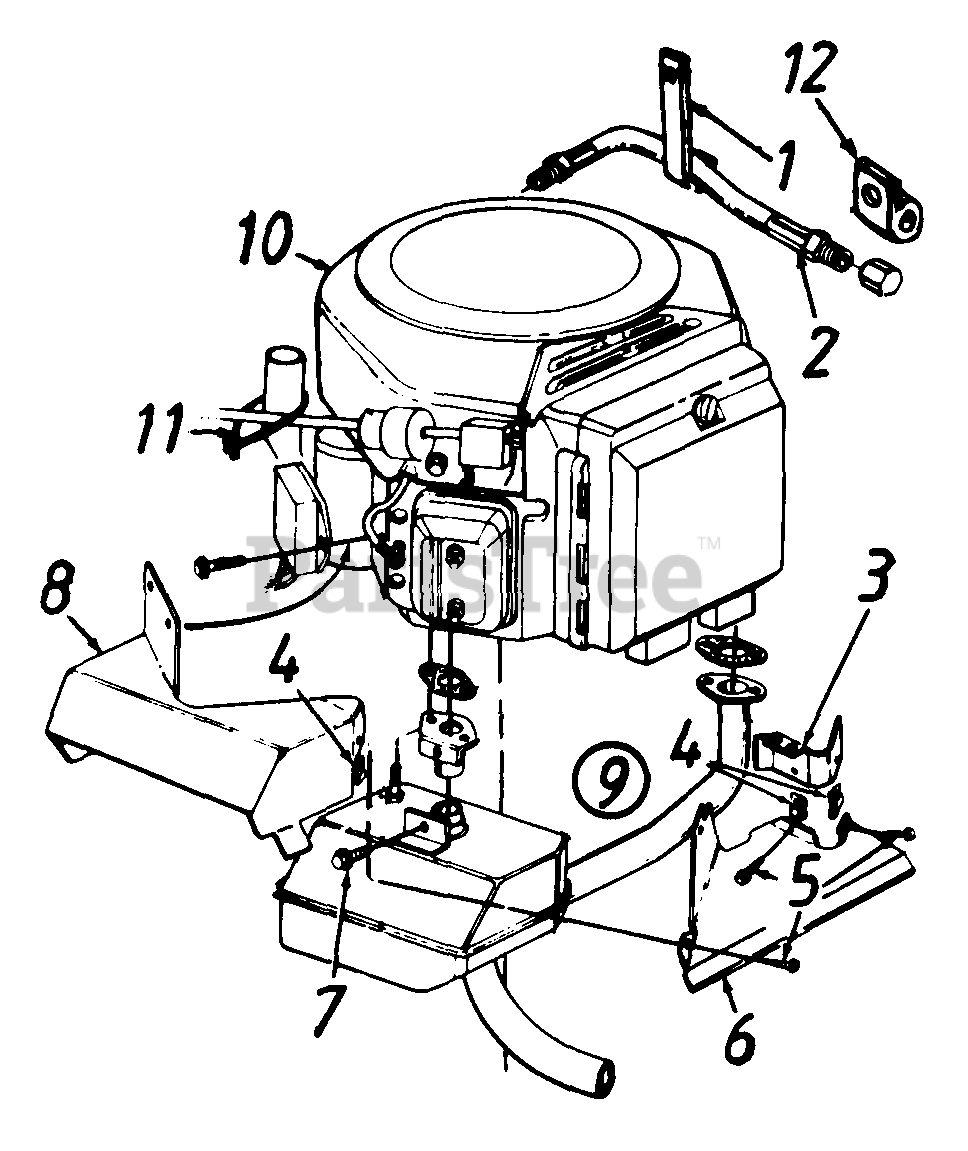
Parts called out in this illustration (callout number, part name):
1	Clamp
2	Hydraulic Hose 13" Lg.
3	Front Heat Shield Ext.
4	Speed Nut #10-24 Thd.
5	Hex B-Tap Scr. #10 x .38" Lg.
6	Front Heat Shield
7	Hex Wash. Hd. TT-Tap Scr. 1/4-20 x .5" Lg.
8	Muffler Heat Shield
9	Muffler Ass'y. Comp.
10	Engine
11	Cable Tie
12	Cable Clip
